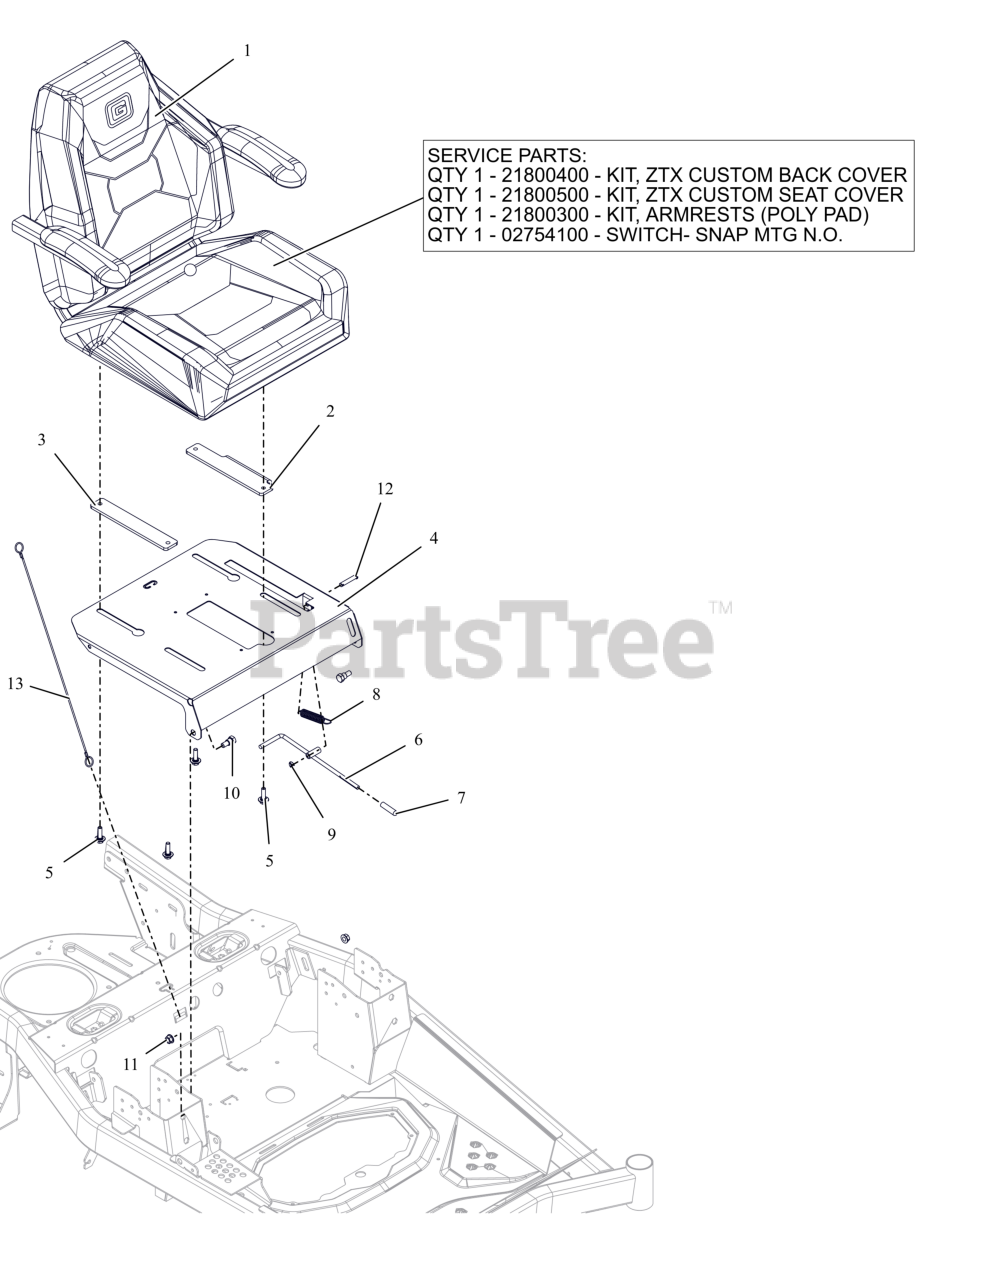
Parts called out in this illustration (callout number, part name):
1	SEAT- ZTX MY23 (WOOD)
1	KIT- ZTX CUSTOM BACK COVER
1	KIT- ZTX CUSTOM SEAT COVER
1	KIT- ARMRESTS ( POLY PAD)
1	SWITCH- SNAP MTG N.O.
2	ADJUSTER-PLATE-SEAT
3	SPCR- SEAT PLATE
4	PLATE-SEATE
5	BLT, SHLDR .31-18 X .100
6	WLDMT- LATCH- SEAT
7	GRIP- BLACK .31X1.50
8	SPRG, EXT .653 X .063 X 2.755
9	NUT-PUSH .312
10	BLT-SHLDR .50X.38 ZCC
11	NUT-LK-CTR-FLG .375-16 GF ZCC
12	PIN, CLEV .309X1.75 ZCC
13	LANYARD, SEAT CABLE .093X19.5
